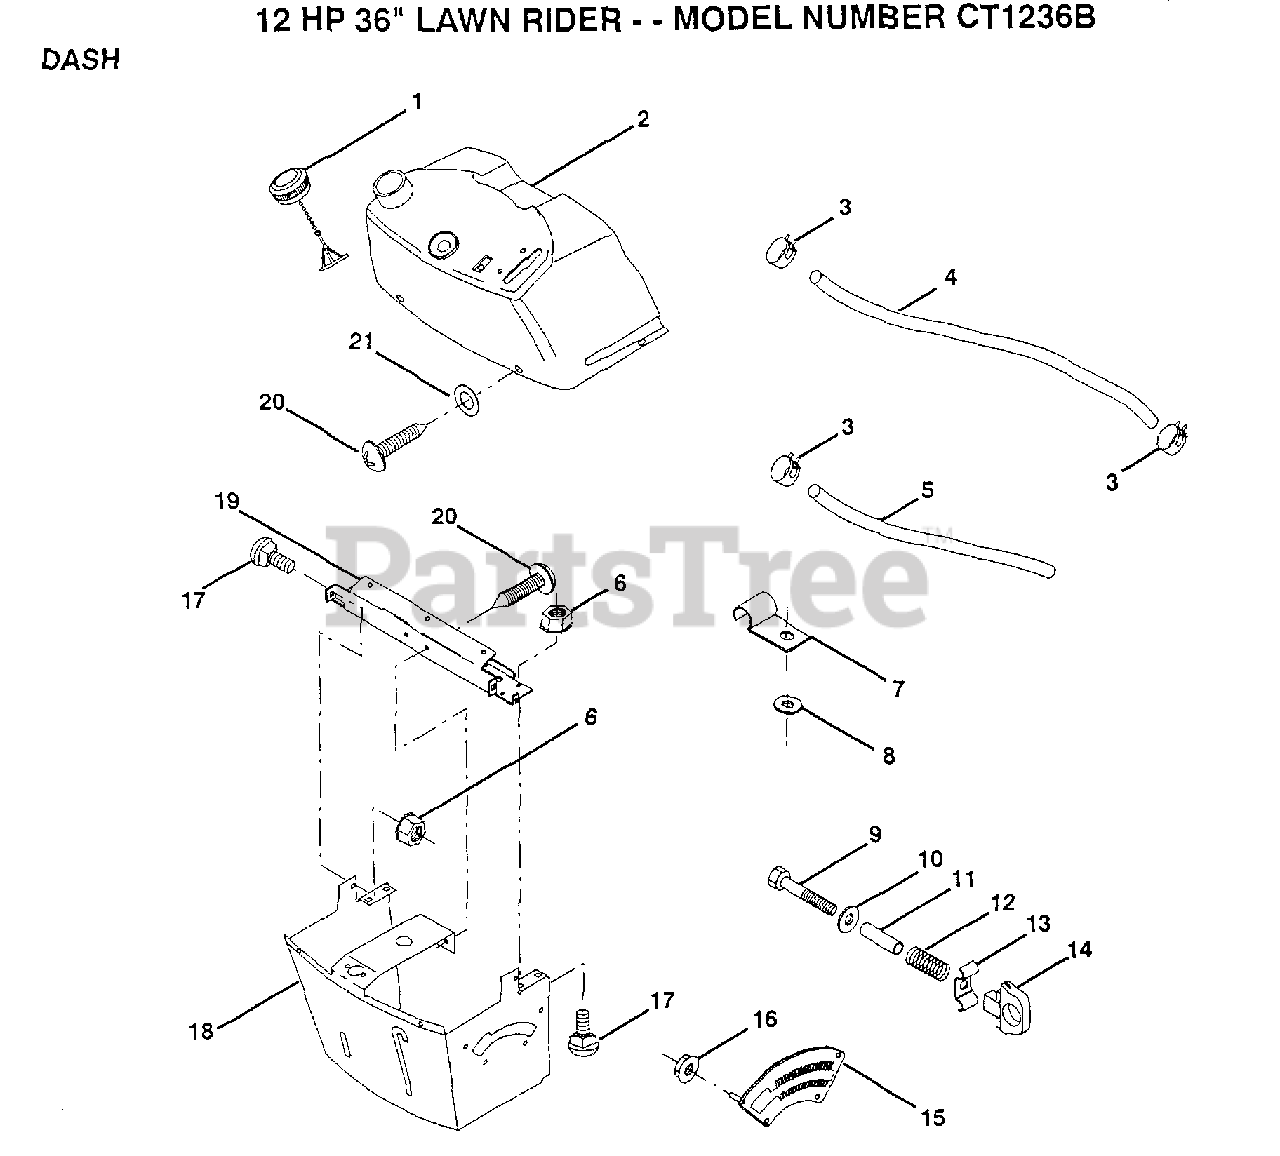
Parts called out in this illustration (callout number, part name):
3	HOSE CLAMP
5	FUEL LINE T
6	NUT
7	CLIP T
8	WASHER PM
9	BOLT
10	WASHER
11	SPACER SPLIT
12	SPRING T
13	GUIDE BELT LH
14	KNOB
15	ADJUSTER QUAD
16	NUT
17	BOLT
18	SUPT ASSY DASH
